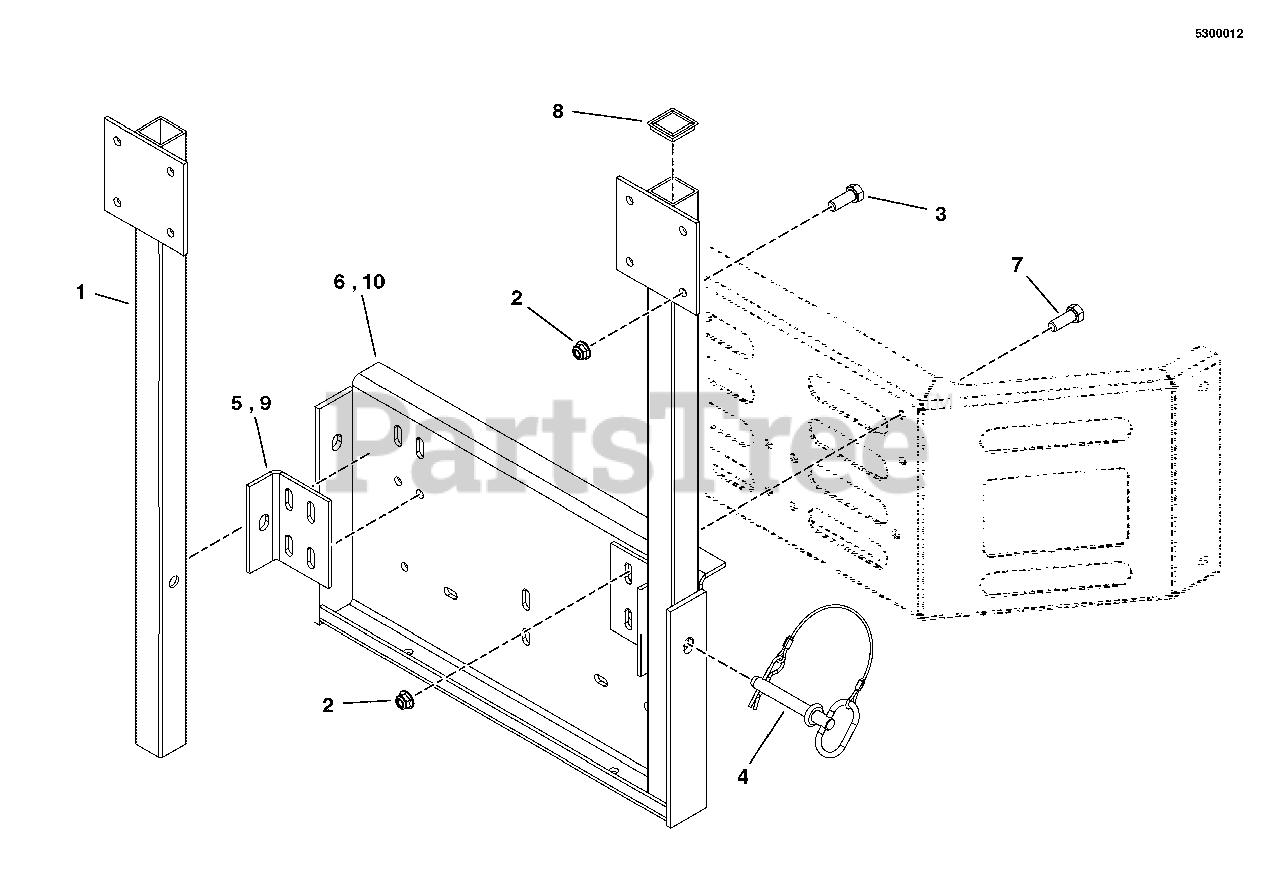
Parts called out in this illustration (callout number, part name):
1	WELD, MOUNT, POST - BLK
2	NUT, 3/8-16 HEX NYLOCK FLANGE
3	BOLT, 3/8-16 X 1 GD5 YZ
4	PIN, HITCH, .50 X 3.25 W/ LANYARD
5	BRACKET, BAGGER MOUNT - BLK
6	WELD, BAGGER MOUNT, IS500 - BLK
7	BOLT, 3/8-16 X 1-1/4 GD5
8	CAP, PLASTIC, 1-1/2 X 1-1/2
9	MOUNT, TAB, BLACK
10	WELD, BAGGER MNT 1500/4500-BLK
